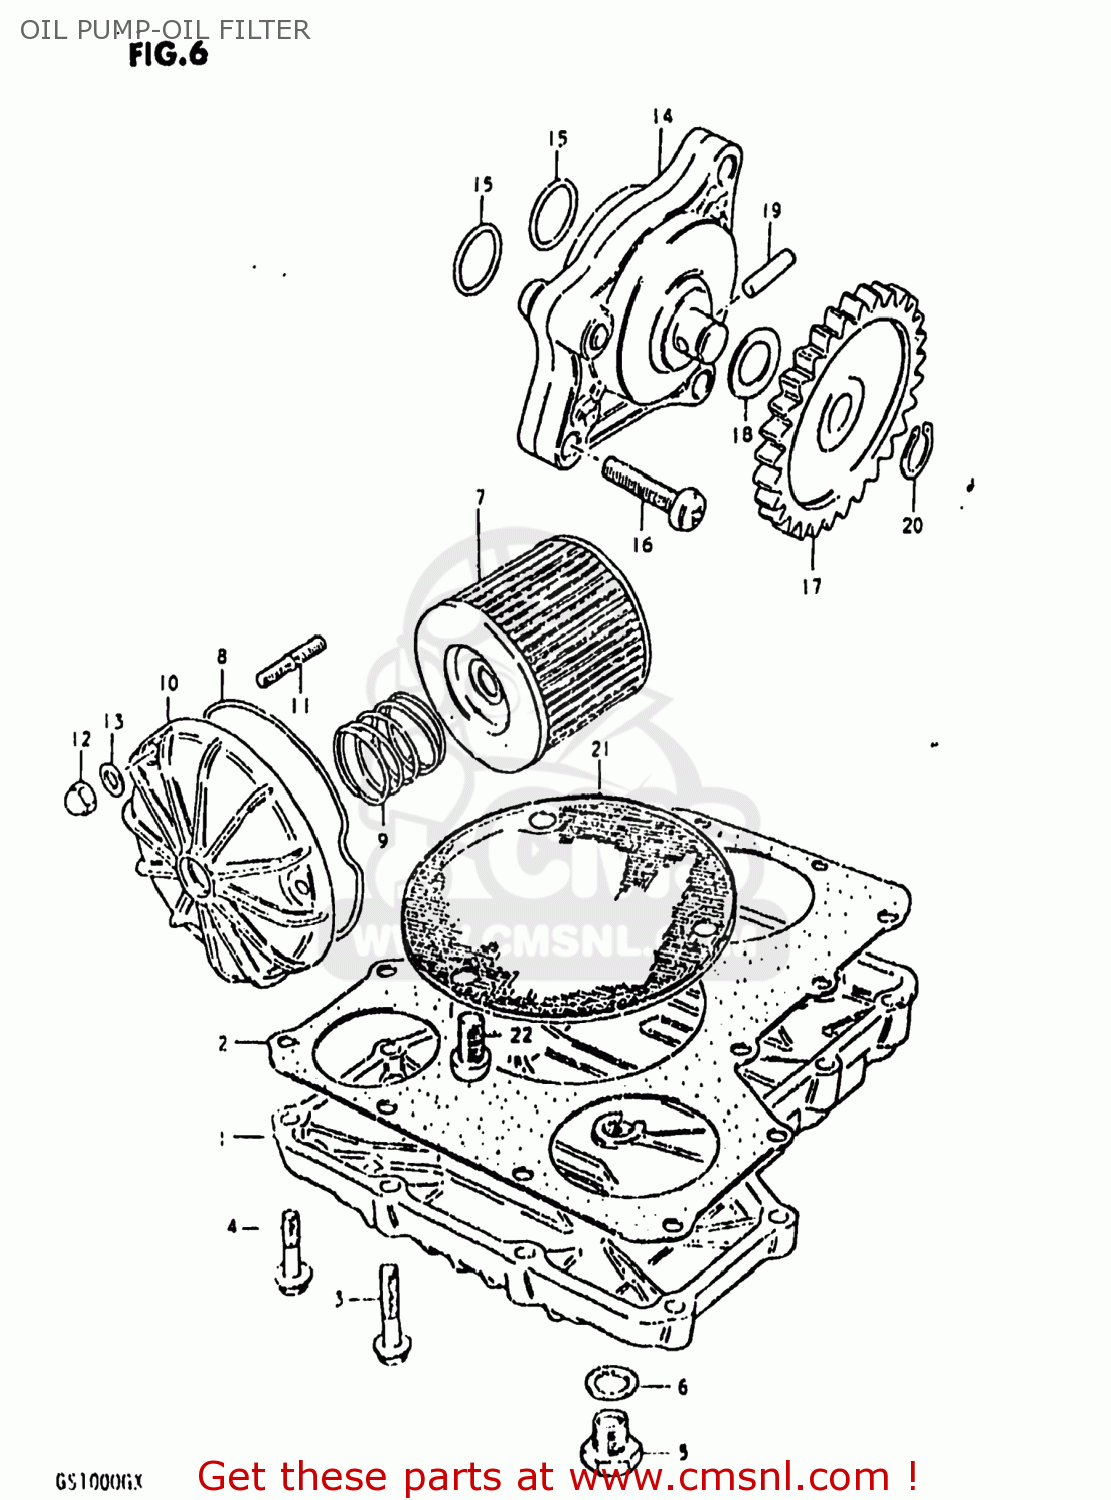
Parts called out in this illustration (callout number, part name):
1	PAN,OIL
2	GASKET,OIL PAN (MCA)
3	BOLT
4	BOLT
5	PLUG
6	GASKET(14X19.2X2) (NAS)
7	FILTER ASSY,ENGINE OIL
8	O RING,OIL FILTER CHAMBER CAP
9	SPRING
10	CAP,OIL FILTER
11	STUD 6X20
12	NUT
13	WASHER
14	PUMP ASSEMBLY,OIL
15	O RING(D:1.9,ID:13)
16	SCREW
17	GEAR,OIL PUMP DRIVEN
18	SHIM
19	PIN(4X15.8)
20	CIRCLIP
21	STRAINER,ENGINE OIL
22	SCREW 6X12
